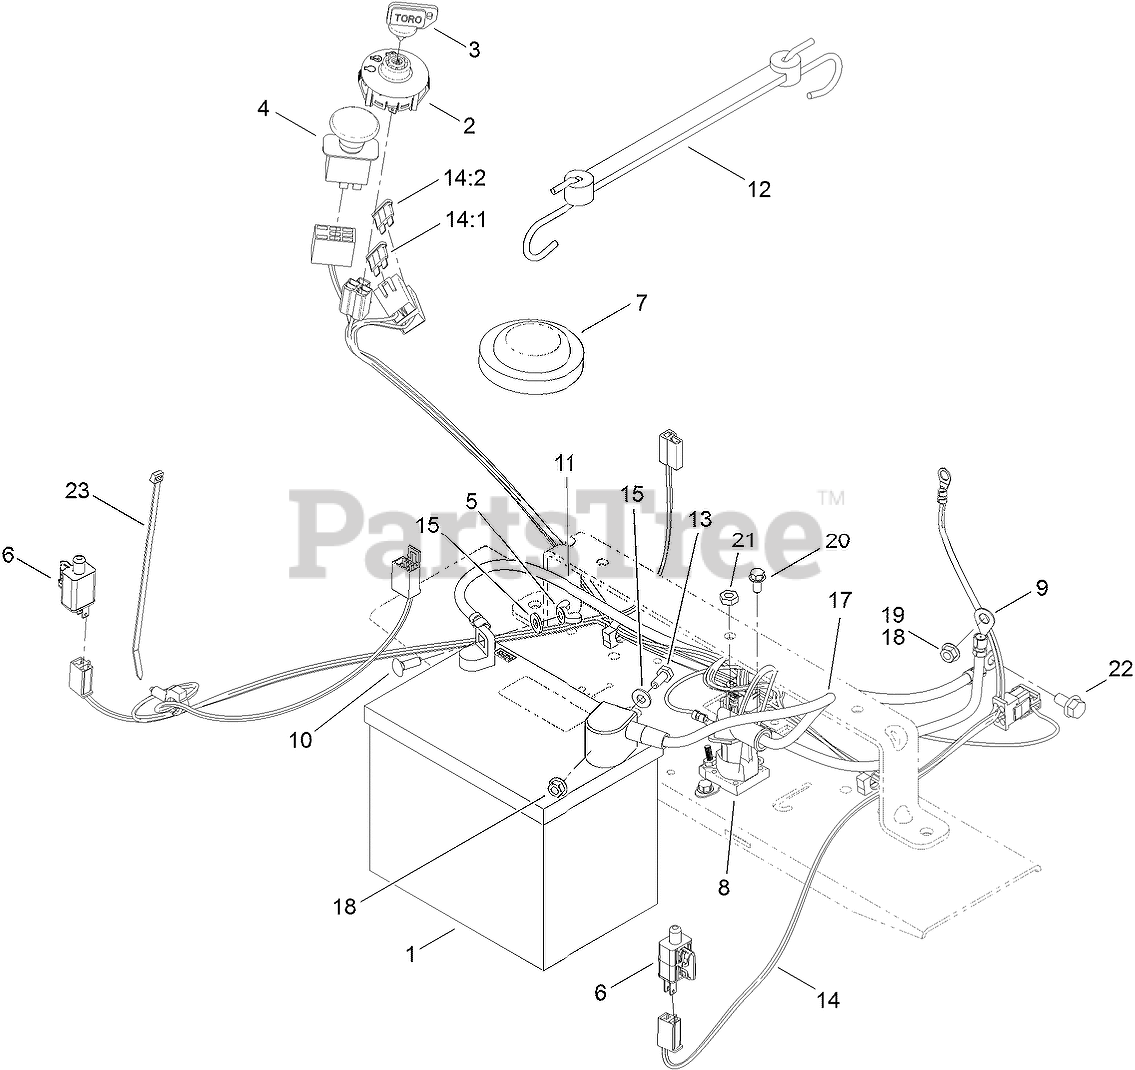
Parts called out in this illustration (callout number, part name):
1	BATTERY
2	SWITCH-IGNITION
3	KEY-IGNITION
4	SWITCH-PTO
5	NUT-WING
6	SWITCH
7	SWITCH-SEAT
8	SOLENOID
9	CABLE-BATTERY, POSITIVE
10	BOLT-CARR
11	CABLE-BATTERY, BLACK
12	HOLDDOWN-BATTERY
13	SCREW-HH
14	HARNESS-WIRE
14:1	FUSE-BLADE, 30 AMP
14:2	FUSE-BLADE, 25 AMP
15	WASHER-FLAT
17	CABLE-BATTERY, RED
18	NUT-HF
19	NUT-HF
20	SCREW-HWH
21	NUT-JAM
22	SCREW-HHF
23	TIE-CABLE
